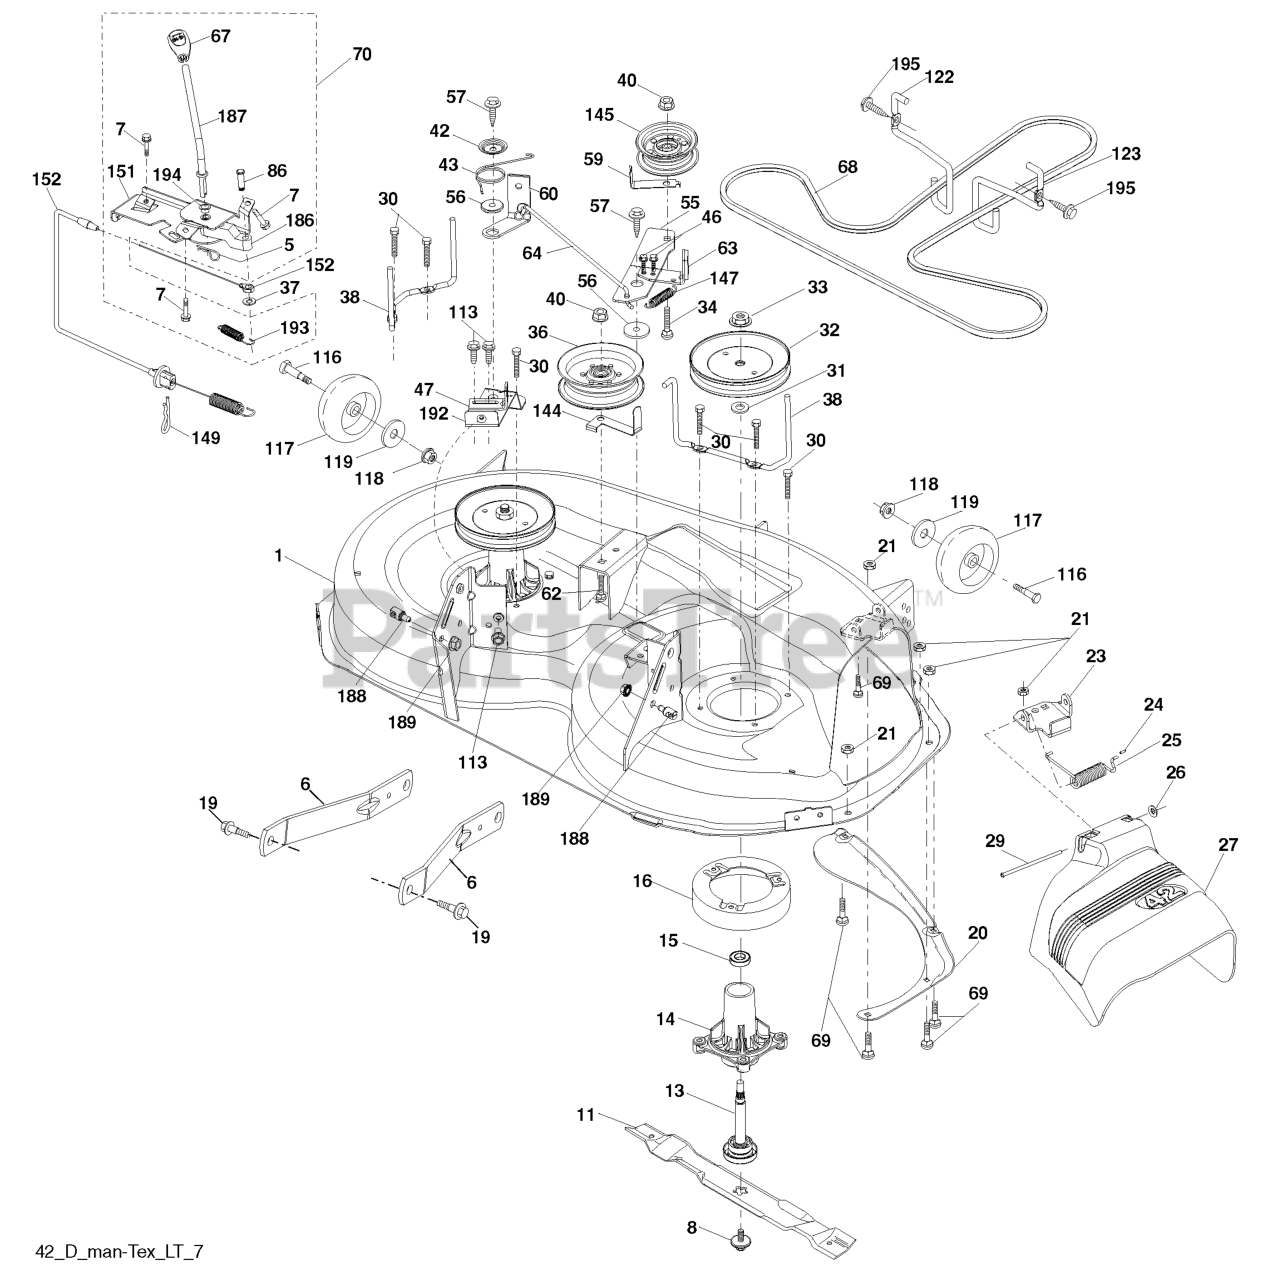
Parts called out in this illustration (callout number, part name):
1	Deck Weldment Mower
5	Retainer Spring
6	Arm Suspension
7	Screw 10 x 3/4 Single Lead Hex
8	Bolt/Washer asm 7/16-20 unf
11	Blade, 42" Hi-Lift (For bagging or discharge)
11	Blade, 42" Mulching Std (For mulching mowers only)
11	Blade, 42" Mulching Premium (For better wear when mulching)
13	Shaft Assembly, Mandrel
14	Housing, Mandrel
15	Bearing, Ball, Mandrel
16	Stripper, Mower Deck
19	Bolt, Shoulder
20	Baffl e, Vortex
21	Nut, Crownlock 5/16-18 unc
23	Bracket, Defl ector
24	Cap, Sleeve
25	Spring, Torsion, Defl ector
26	Nut, Push
27	Shield, Defl ector
29	Rod, Hinge
30	Screw Thdrol Rolling Wsh Hd
31	Washer, Spacer
32	Pulley, Mandrel
33	Nut, Toplock, Flanged
34	Bolt Carr Sh. 3/8-16 x 1-1/2 Gr. 5
36	Pulley, Idler, Flat
37	Washer
38	Keeper Belt LH Mandrel
40	Nut, Lock Flg. 3/8-16 unc
42	Spring Torsion Brake
43	Spring Torsion Retainer
46	Screw Thd Roll 1/4-20 x 5/8
47	Bracket Clutch Cable
54	Washer, Hardened
55	Arm, Idler
56	Spacer, Retainer
57	Screw 3/8-16 x 1
59	Guard, Tuv Idler
60	Arm Brake Mower
62	Bolt Rd Hd Sq Nk 3/8-16 unc x 2
63	Arm Brake Mower
64	Link Brake Asm
65	Spacer Retainer
67	Handle Clutch Cable
68	V-Belt
69	Bolt
70	Clutch Asm Manual
86	Pin Attachment Cable
87	Switch Interlock Clutch Cable
88	Screw 10-24 x 5/8
113	Bolt 5/16-18
116	Bolt, Shoulder
117	Wheel, Gauge
118	Nut, Crownlock 3/8-1
119	Washer 13/32 x 7/8 x 14 Ga.
122	Keeper Belt Engine LH
123	Keeper Belt Engine RH
144	Keeper Belt
145	Pulley Idler
147	Spring Return
149	Retainer Spring
151	Bracket Clutch
152	Manual Clutch Cable
186	Arm Actuator
187	Lever Control
188	Stud Fastener
189	Nut Lock Hex Flange
192	Bracket Brake Stand LH
193	Spring Plunger Activator
194	Bearing Control Lever Clutch
195	Screw Hex Wsh THDR 3/8-16 x 3/4
195	Mandrel Assembly
195	Replacement Mower, Complete
